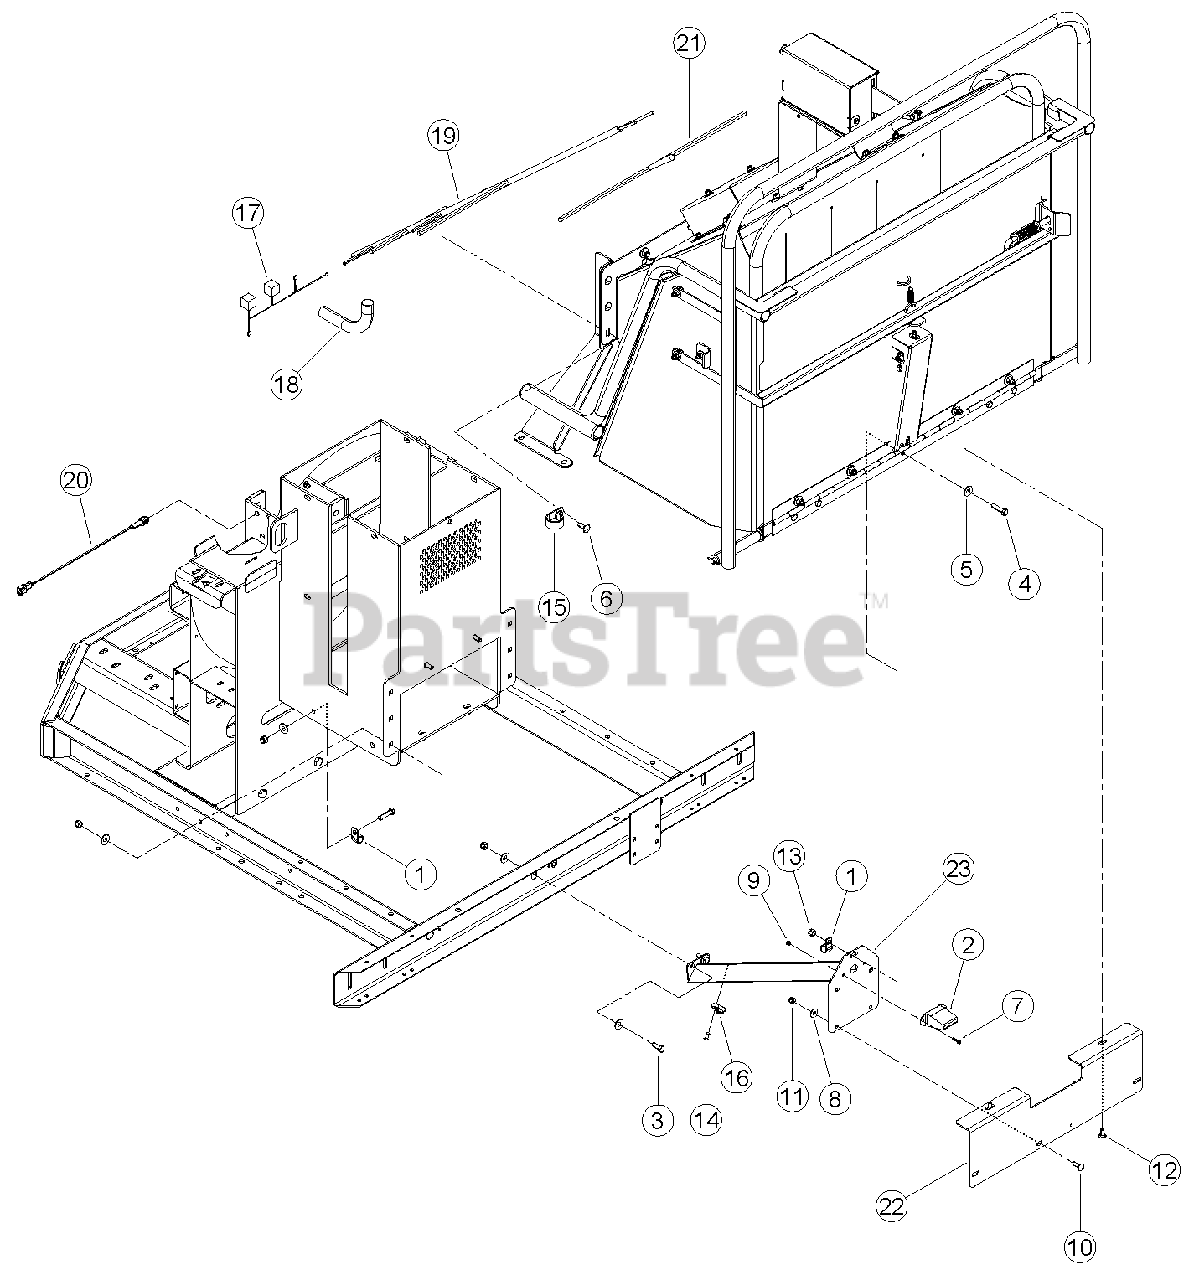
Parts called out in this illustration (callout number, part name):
1	CLAMP, 9/16 COATED
2	LIGHT, LICNESE PLATE
3	BOLT, 3/8 NC X 1 HEX HD GR5 ZP
4	BOLT, 3/8 NC X 1-1/2 HEX HD
5	WASHER, 3/8 FLAT ZP
6	BOLT, 3/8 X 1 CRG
7	SCREW, #10 X 3/4 HEX TAP SC
8	WASHER, 5/16 FLAT ZP
9	NUT, 8-32 NYLOCK
10	BOLT, 5/16 X 1 CRG ZP
11	NUT, 5/16 NE NYLOCK ZP
12	BOLT, 5/16 X 3/4 CRG ZP
13	NUT, 3/8 NE NYLOCK ZP
14	RIVET, AL BLIND 1/4 X 3/4 DOME HEAD
15	CLAMP, 1-9/16 COATED
16	CLAMP, CABLE MOUNT
17	HARNESS, CHIPPER SAFETY RELAY
18	SLEEVING, BRAIDED ELECTRICAL HARNESS
19	HARNESS, 6" GAS PLUS 1 CONTROLLER
20	SENSOR, M12 PNP PROXIMITY
21	HARNESS, SAFETY BAR
22	BRACKET, EUROPEAN LISENCE
23	WELDMENT, CHUTE SUPPORT
